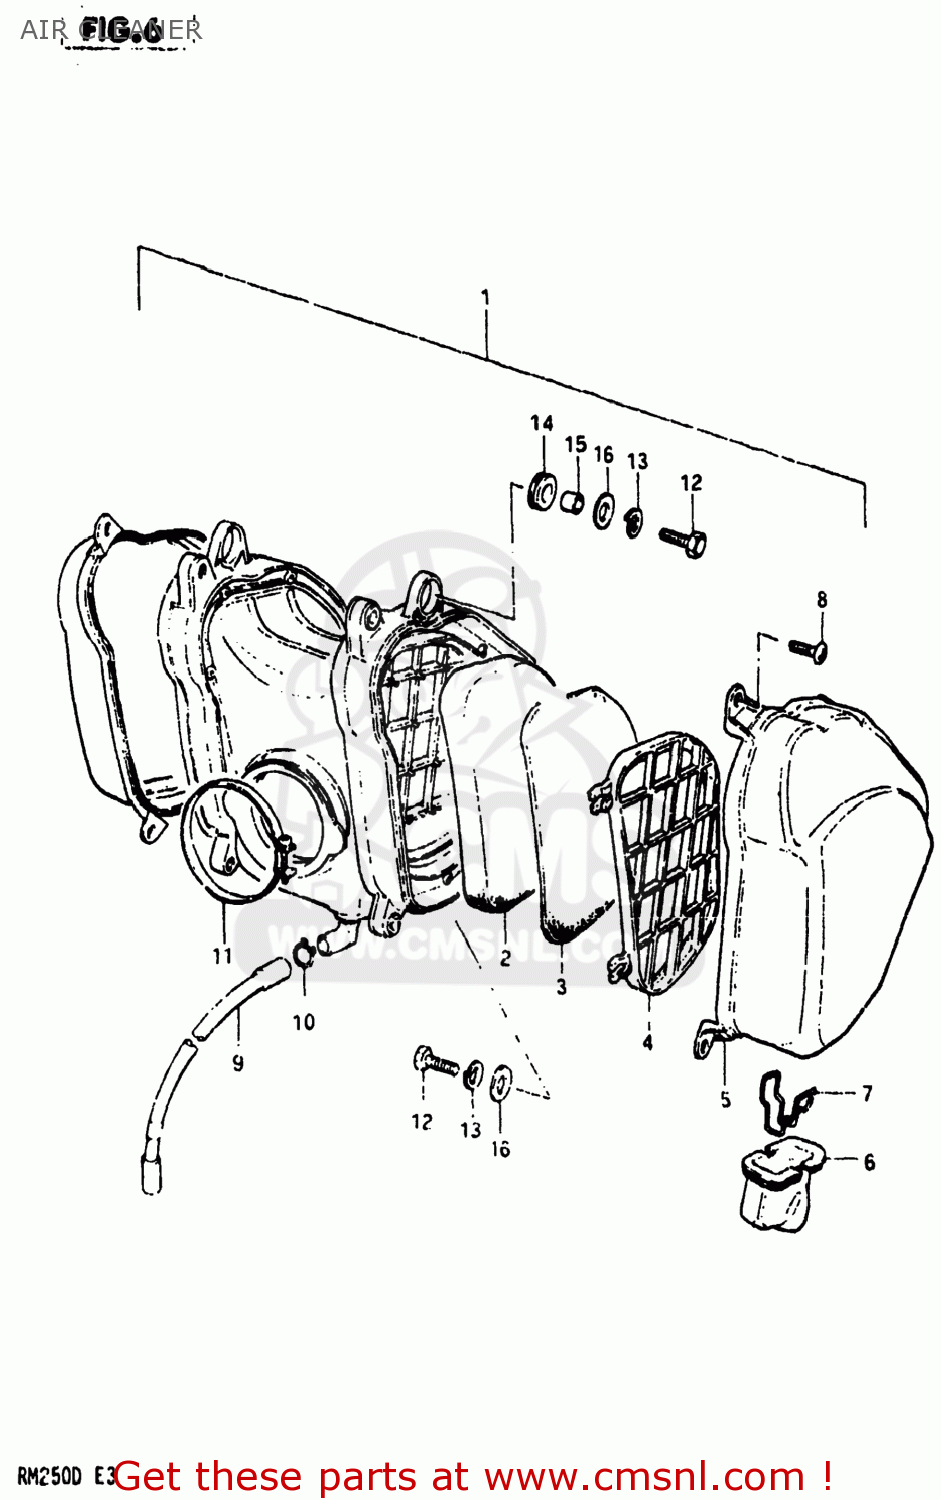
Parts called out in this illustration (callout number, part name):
1	CLEANER ASSEMBLY,AIR
2	FILTER
3	FILTER,2ND
4	HOLDER,AIR CLEANER,LEFT
5	CAP,AIR CLEANER,LEFT
6	DRAIN TUBE
7	DRAIN STOPPER
8	SCREW
9	DRAIN TUBE
10	CLIP
11	CLAMP
12	BOLT
13	LOCK WASHER
14	CUSHION
15	SPACER (7X9X7)
16	WASHER
